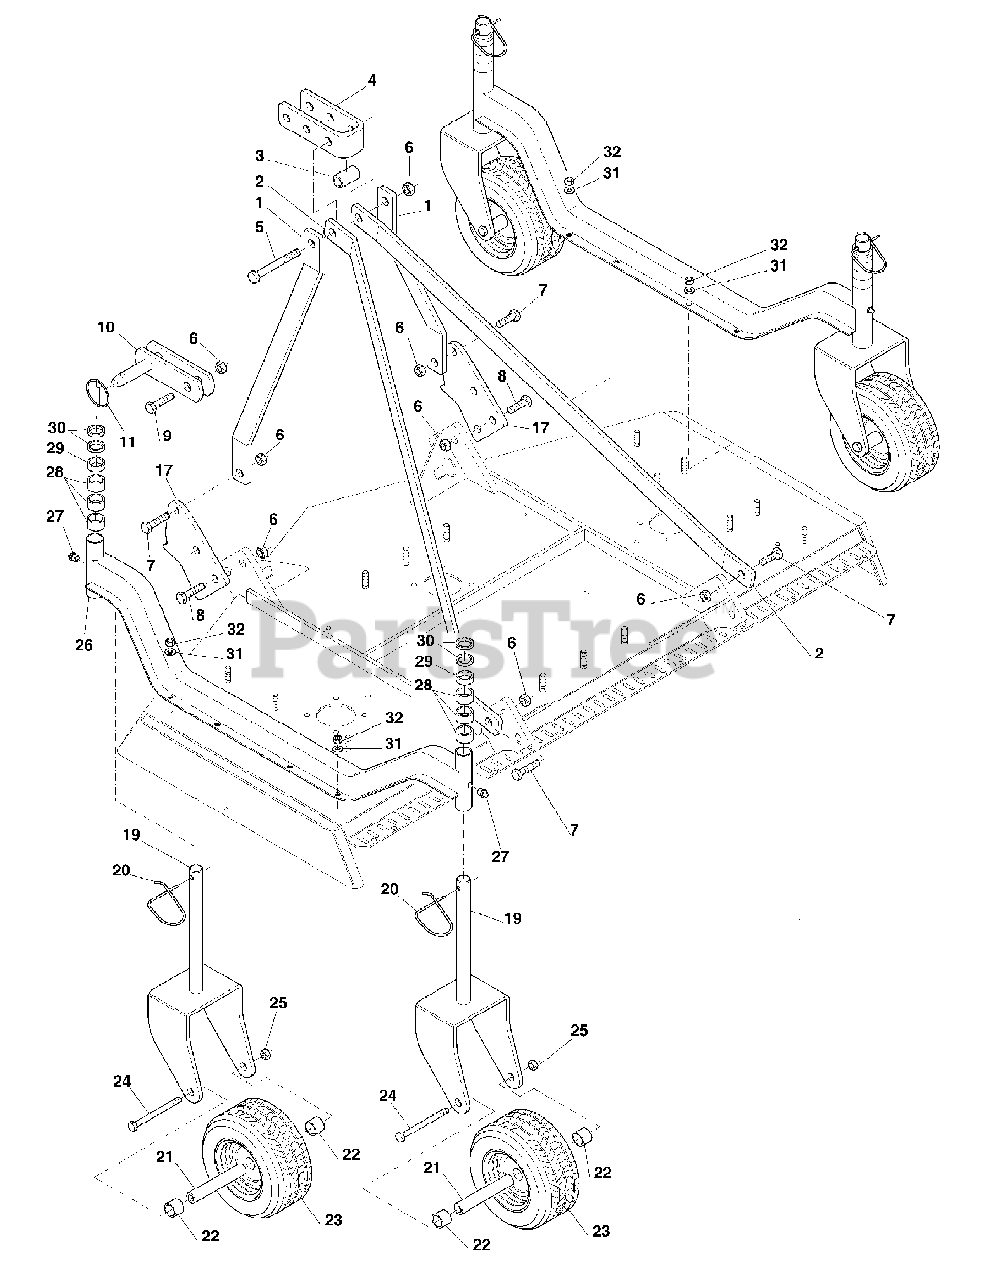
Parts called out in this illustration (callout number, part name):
1	Top hitch support
2	Top hitch arm FML72
3	Spacer
4	Upper plate
5	Bolt TE 16x140
6	Nut M16
7	Bolt TE 16x45
8	Bolt TE 16x50
9	Bolt TE 16x55
10	Hitch block
11	Lynch pin
17	Linking plate FML72
19	Wheel yoke
20	Cotter pin
21	Inner spacer
22	Hard tire outer wheel spacer
23	Hard tire
24	Bolt TE 14x150
25	Nut M14
26	Wheel arm FML72
27	Grease fitting
28	Spacer 1"
29	Spacer 1/2"
30	Spacer 1/4"
31	Flat washer Ø10
32	Nut M10
